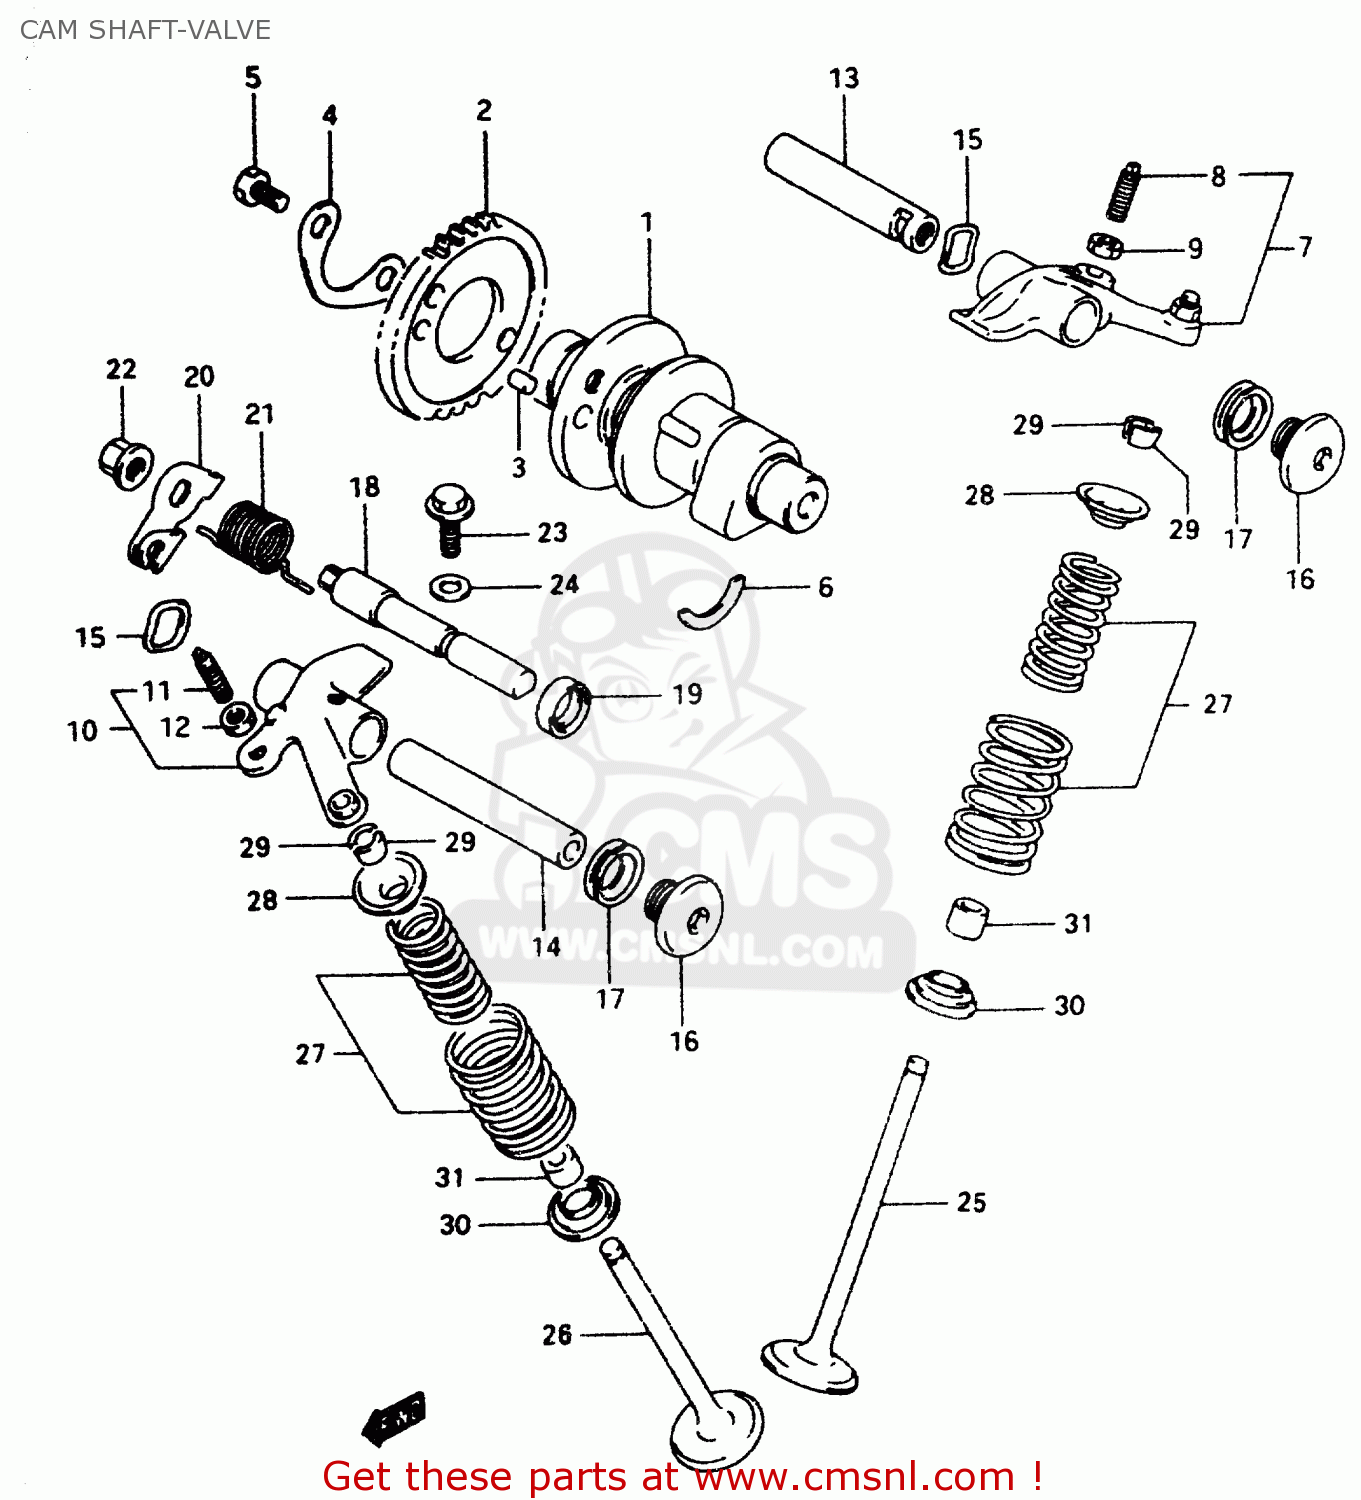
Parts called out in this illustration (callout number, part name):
1	SHAFT COMP,CAM
2	SPROCKET,CAMSHAFT
3	PIN(5X8)
4	WASHER,SPROCKET
5	BOLT(6X10.5)
6	C RING
7	ARM,VALVE ROCKER,INTAKE
8	SCREW,TAPPET ADJUSTING
9	NUT,TAPPET ADJUSTING
10	ARM,VALVE ROCKER EXHAUST
11	SCREW,TAPPET ADJUSTING
12	NUT,TAPPET ADJUSTING
13	SHAFT,VALVE ROCKER ARM INTAKE
14	SHAFT,VALVE ROCKER ARM EXHAUST
15	WASHER
16	PLUG,14X12
17	GASKET(13.8X18.8X4.8) (NAS)
18	SHAFT,DECOMP
19	SEAL,OIL(10X17X6)
20	LEVER,DECOMPRESSION SHAFT
21	SPRING
22	NUT
23	BOLT
24	GASKET(6.4X11.5X0.8) (NAS)
25	VALVE,INTAKE
26	VALVE,EXHAUST
27	SPRING SET,VALVE
28	RETAINER,VALVE SPRING
29	COTTER VALVE
30	SEAT,VALVE SPRING
31	SEAL,OIL(5X10X9.7)
